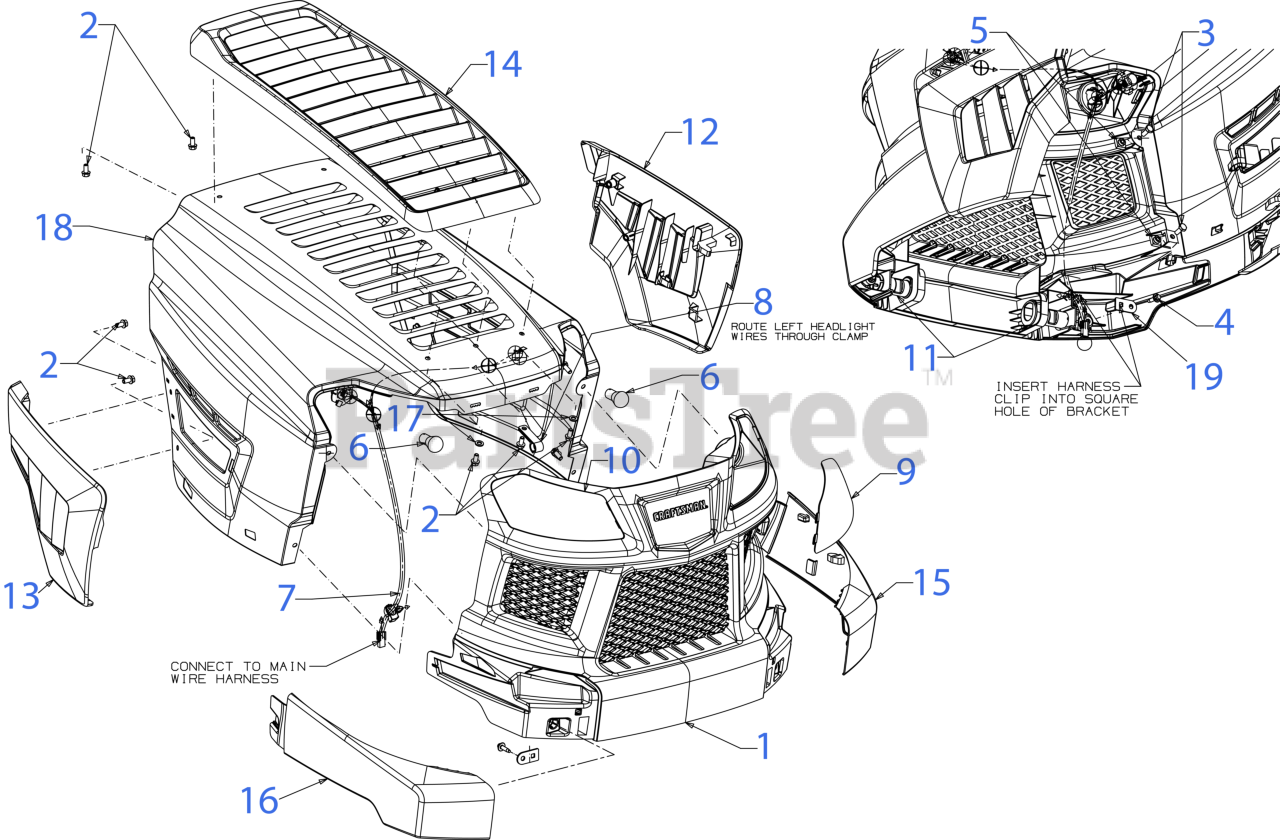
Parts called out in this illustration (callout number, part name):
1	GRILLE
2	HEX SCREW 1/4-15 x .50
3	SCREW 1/4-20 x .62 SPEC GR5
4	SCREW 1/4-10 x .750
5	SQUARE NUT 1/4-20
6	MINIATURE LAMP-12V #1156
7	HEADLIGHT HARNESS
8	HEADLIGHT HARNESS CLAMP
9	GRILLE LENS (LH)
10	GRILLE LENS (RH)
11	HOOD PIVOT PIN
12	HOOD SIDE COVER (LH)
13	HOOD SIDE COVER (RH)
14	HOOD SCOOP
15	GRILLE PANEL (LH) (LIBERTY RED)
16	GRILLE PANEL (RH) (LIBERTY RED)
17	FLAT WASHER .281 x .50 x .063
19	HARNESS CLIP BRACKET
